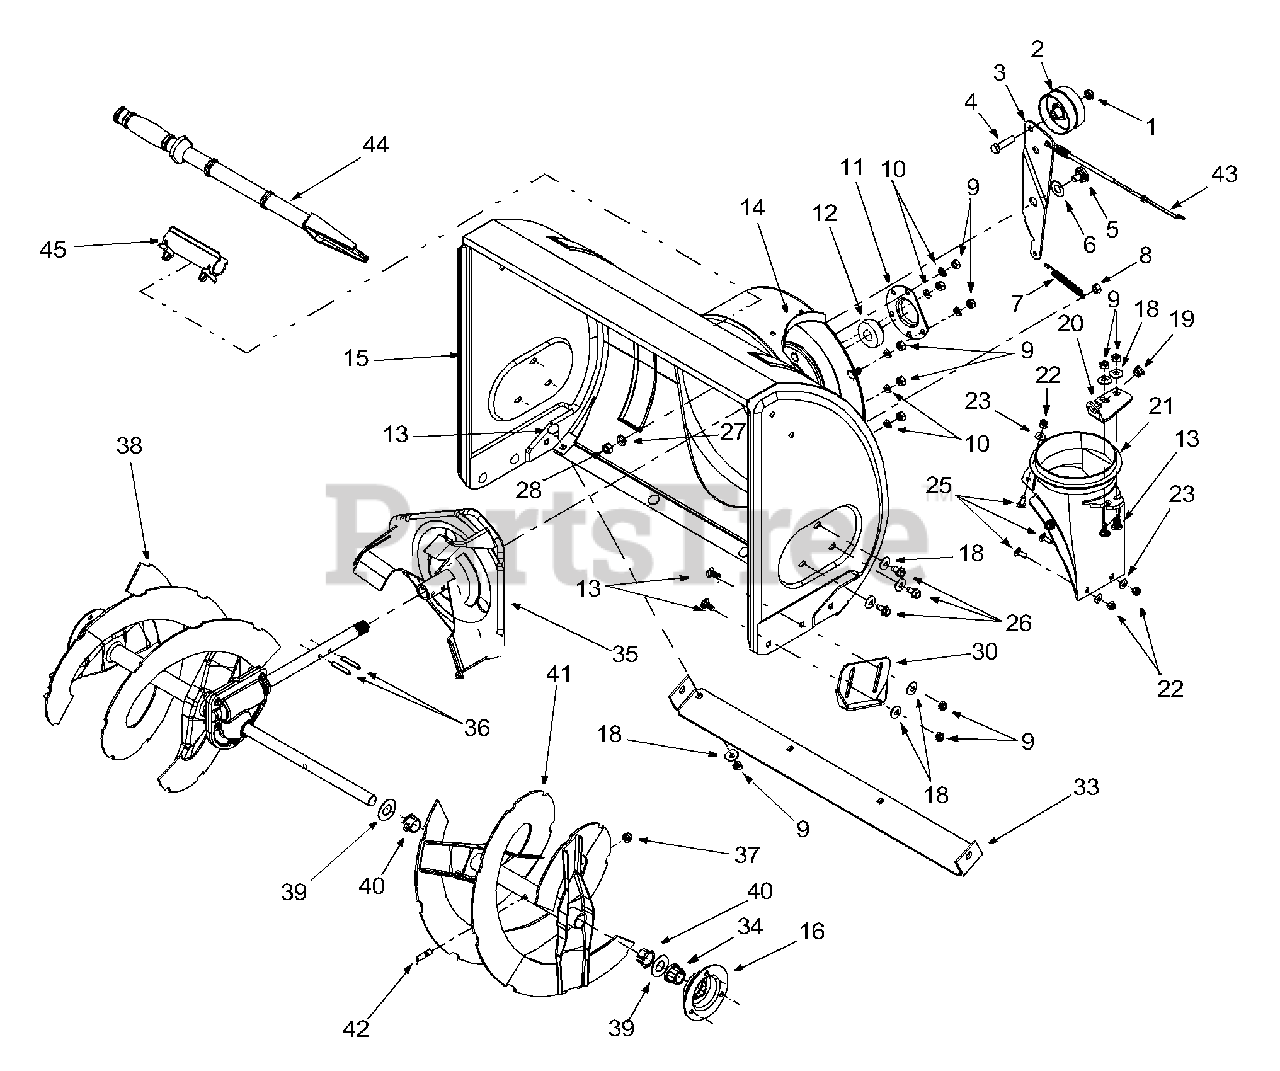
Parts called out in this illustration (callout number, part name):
1	Lock Jam Nut 3/8-24
2	Flat Idler
4	Hex Cap Screw 3/8-24 x 1.50
5	Shoulder Screw
6	Flat Washer, .565 x 1.25 x .02
7	Extension Spring
8	Hex Nut 5/16-18
9	Hex Nut 5/16-18
10	Lock Washer 5/16
11	Housing
12	Ball Bearing
13	Carriage Bolt 5/16-18 x .75
18	Bell Washer
19	Bushing
21	Chute Adapter
22	Hex Lock Nut 1/4-20
23	Flat Washer
25	Carriage Screw 1/4-20 x .75
26	Hex Washer TT Screw 5/16-18
27	Lock Washer 3/8
28	Hex Nut 3/8-16
34	Hex Flange Bearing
37	Lock Nut 5/16-18
39	Flat Washer
40	Flange Bushing
42	Shear Bolt 5/16-18 x 1.5
43	Drive Cable
44	Chute Clean-out Tool
45	Mount, Chute Clean-out Tool
